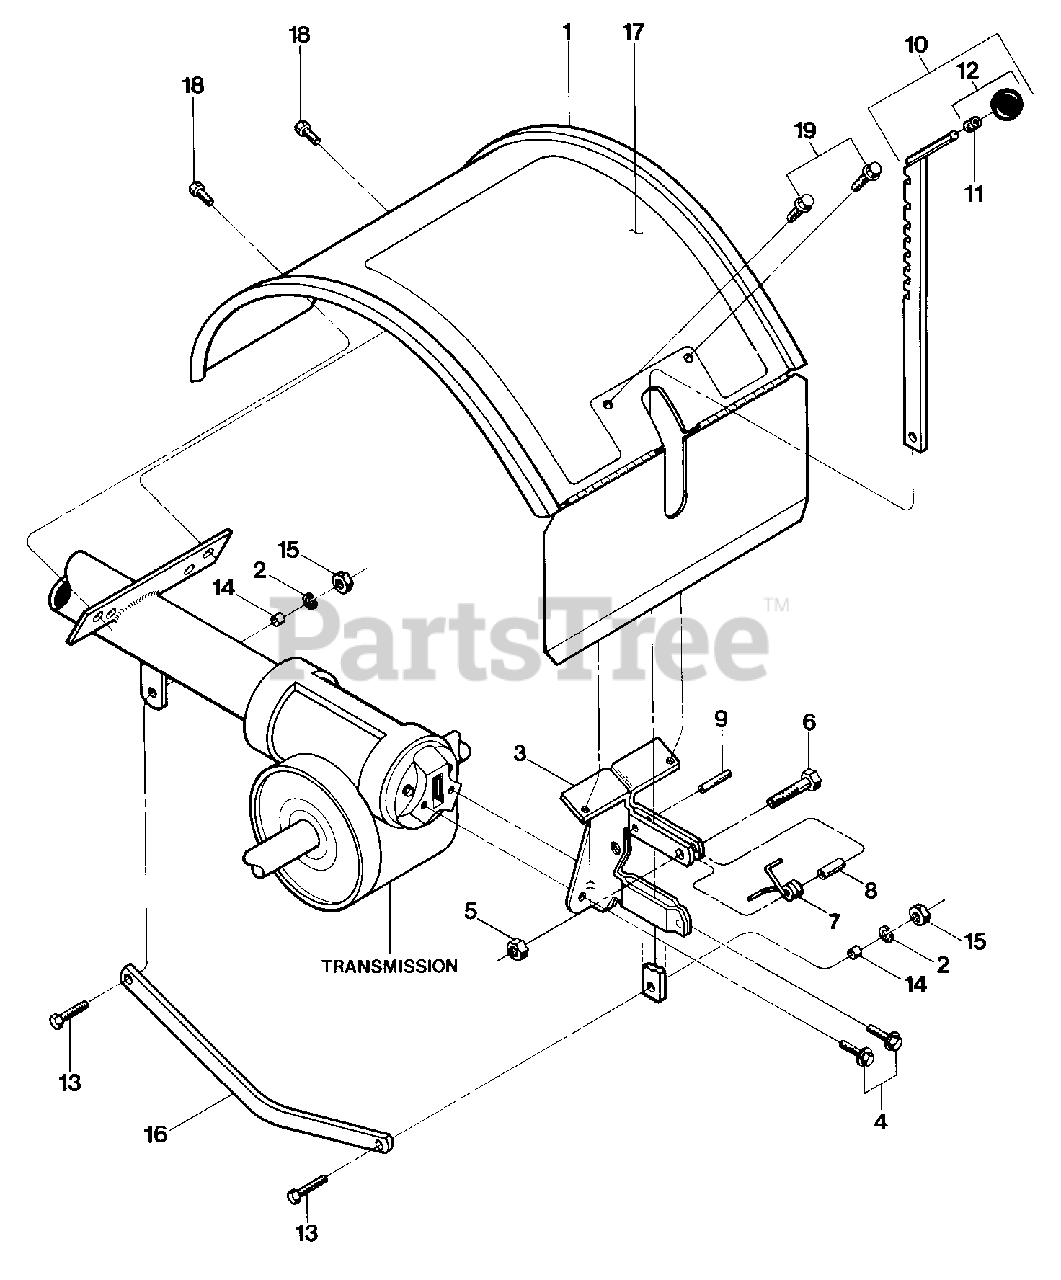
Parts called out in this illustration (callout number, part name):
1	Hood-Tine cover, with hinged flap
2	Lockwasher, 3/8
3	Bracket-Hood & Depth Regulator
4	Screw-flanged hex hd., 5/16-18 x 5/8
5	Hex Locknut, 1/4-20
6	Hex Hd. Screw, 1/4-20 x 1
7	Spring-Depth regulator plunger
9	Roll Pin-1/4 x 1 (spiral)
10	Bar Assembly-Depth adjustment
11	Ring-Retaining, tolerance ring
12	Knob-Depth regulator
13	Hex Hd. Screw, 3/8-16 x 1-1/4
14	Bushing-Spacer
15	Hex Nut, 3/8-16
16	Drag Bar
17	Decal-Tiller operating instructions
18	Hex Hd. Screw, self-tapping, 5/16-18 x 1/2
19	Screw-flanged hex hd, self-tapping, 1/4-20 x 1/2
